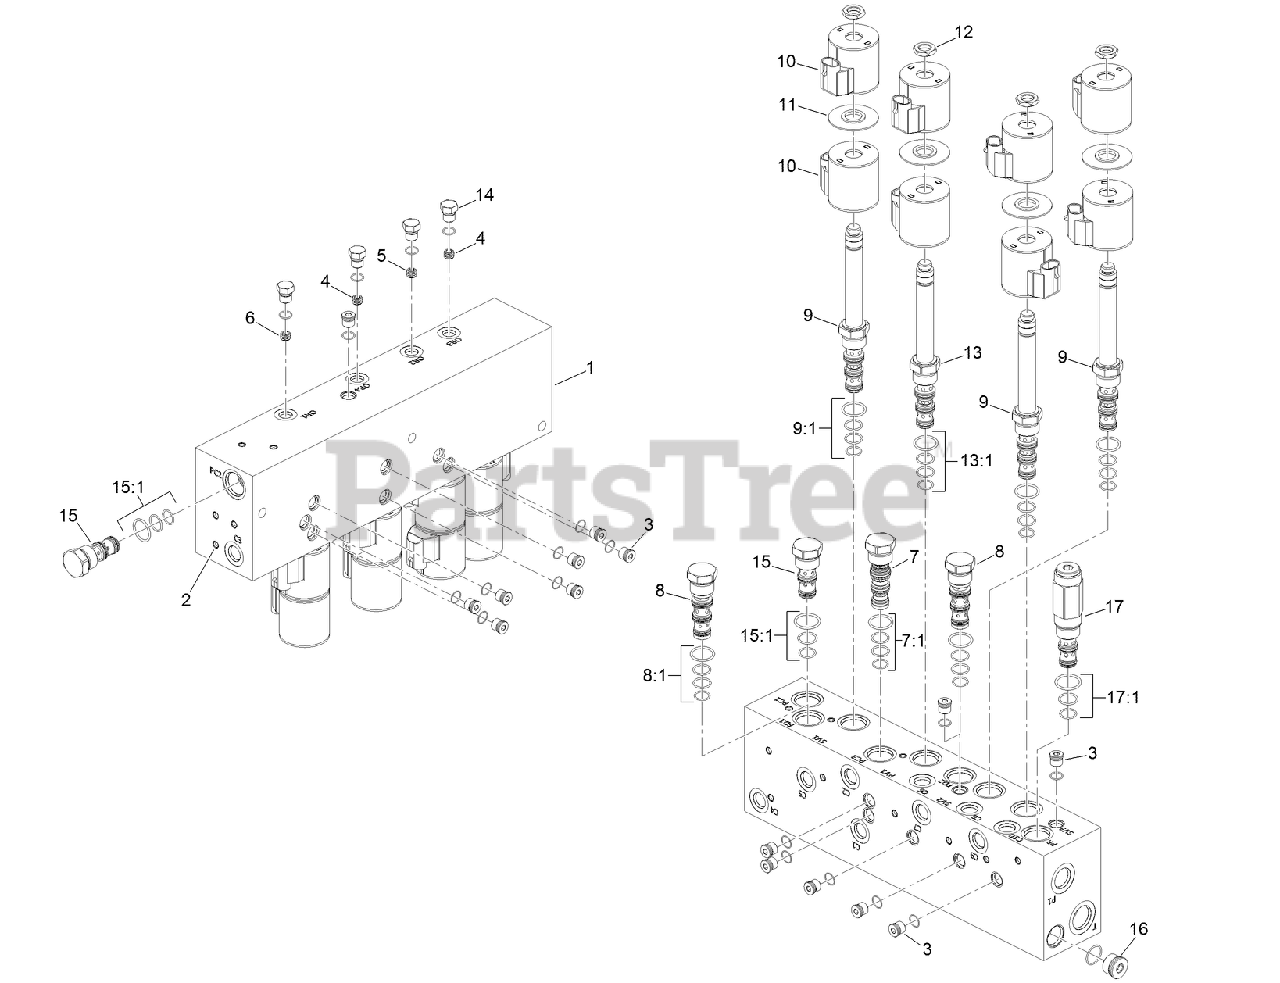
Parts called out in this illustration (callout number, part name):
1	BLOCK-MANIFOLD
2	Deck ASM
4	ORIFICE
5	ORIFICE
6	ORIFICE
7	VALVE-CHECK
7:1	SPOOL VALVE SEAL KIT
8	VALVE-FLOW DIVIDER/COMBINER
8:1	SEAL KIT
9	VALVE-CARTRIDGE, MOTOR SPOOL
9:1	SPOOL VALVE SEAL KIT
10	COIL-12V, DC
11	SPACER-E COIL
12	NUT-COIL
13	SOLENOID ASM
13:1	SPOOL VALVE SEAL KIT
15	VALVE-CHECK, P O
15:1	SEAL KIT
16	PLUG-HYD
17	VALVE-REDUCING, PRESSURE
17:1	SEAL KIT
